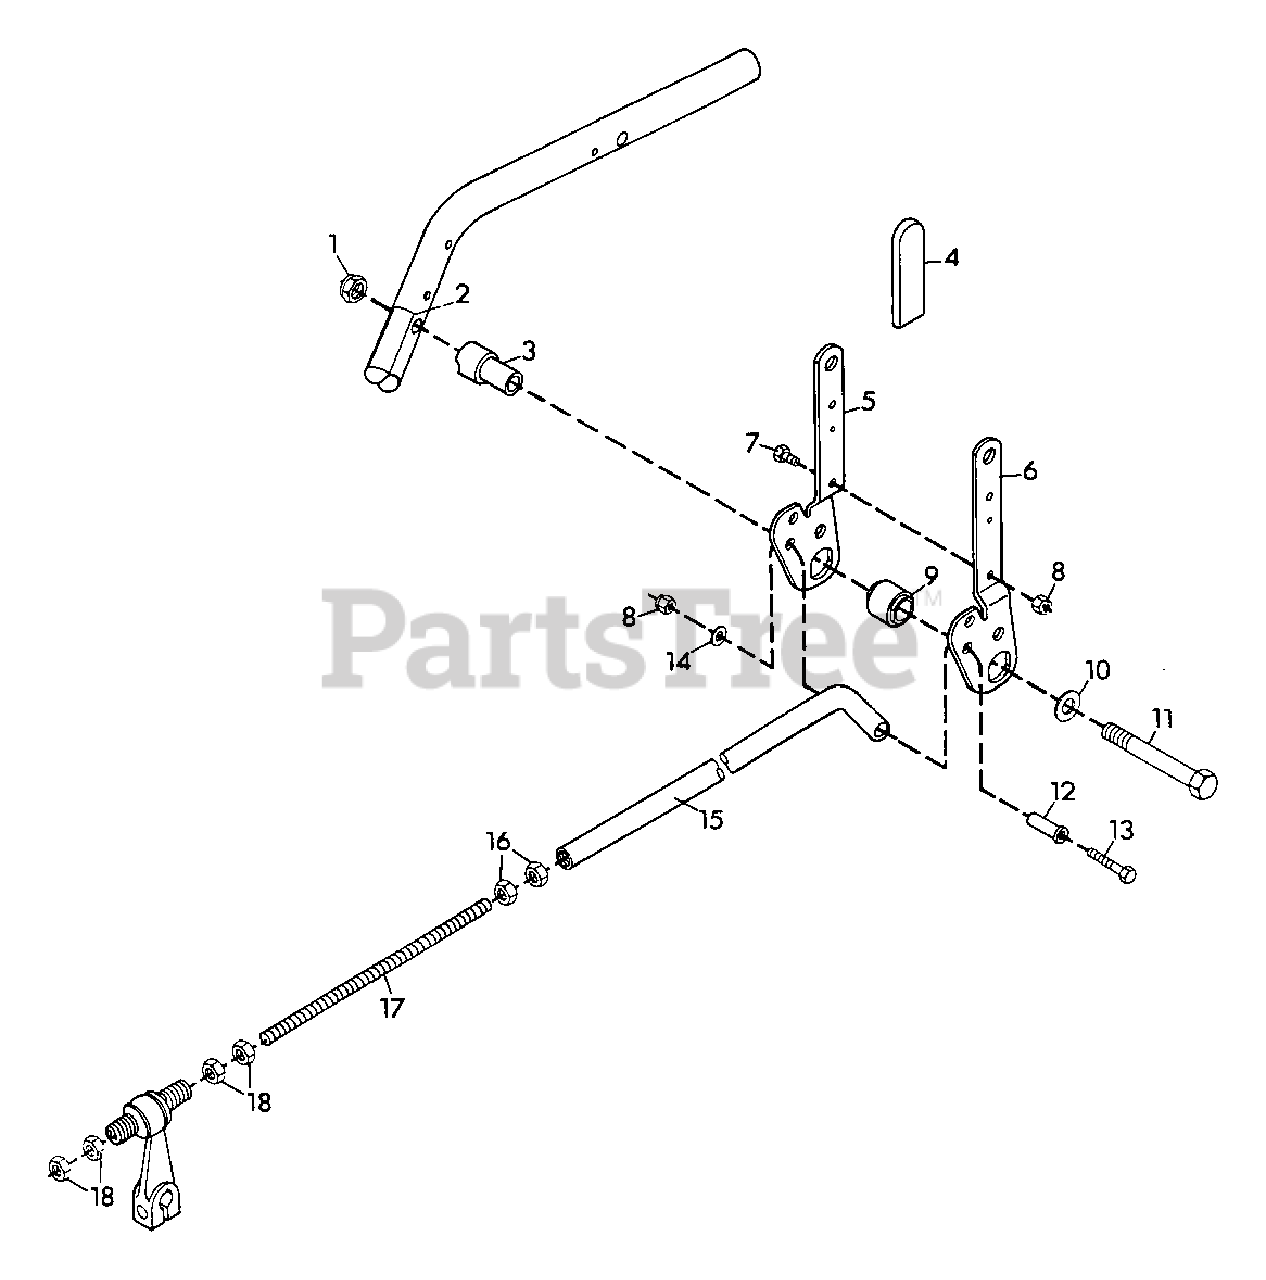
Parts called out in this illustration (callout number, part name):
1	Nut, Lock 1/2-23 E.T.
2	Decal, Gear Shift
3	Pivot, Hand Lever L.H.
4	Grip, Handle
5	Handle, Control R.H.
6	Handle, Control L.H.
7	Bolt, Hex 1/4-20x.625
8	Nut, Lock 1/4-20
9	Bushing, Handle
10	Washer, Flat .531x1.062x.095
11	Bolt, Hex 1/2-13x3.50
12	Bushing, Operator Presence Handle
13	Bolt, Hex 1/4-20x1.50
14	Washer, Flat .281x.625x.065
15	Rod, Control Hi-Lo
16	Nut, Hex 3/8-16
17	Rod, Control Extension
18	Nut,Jam 3/8-16 Hex
